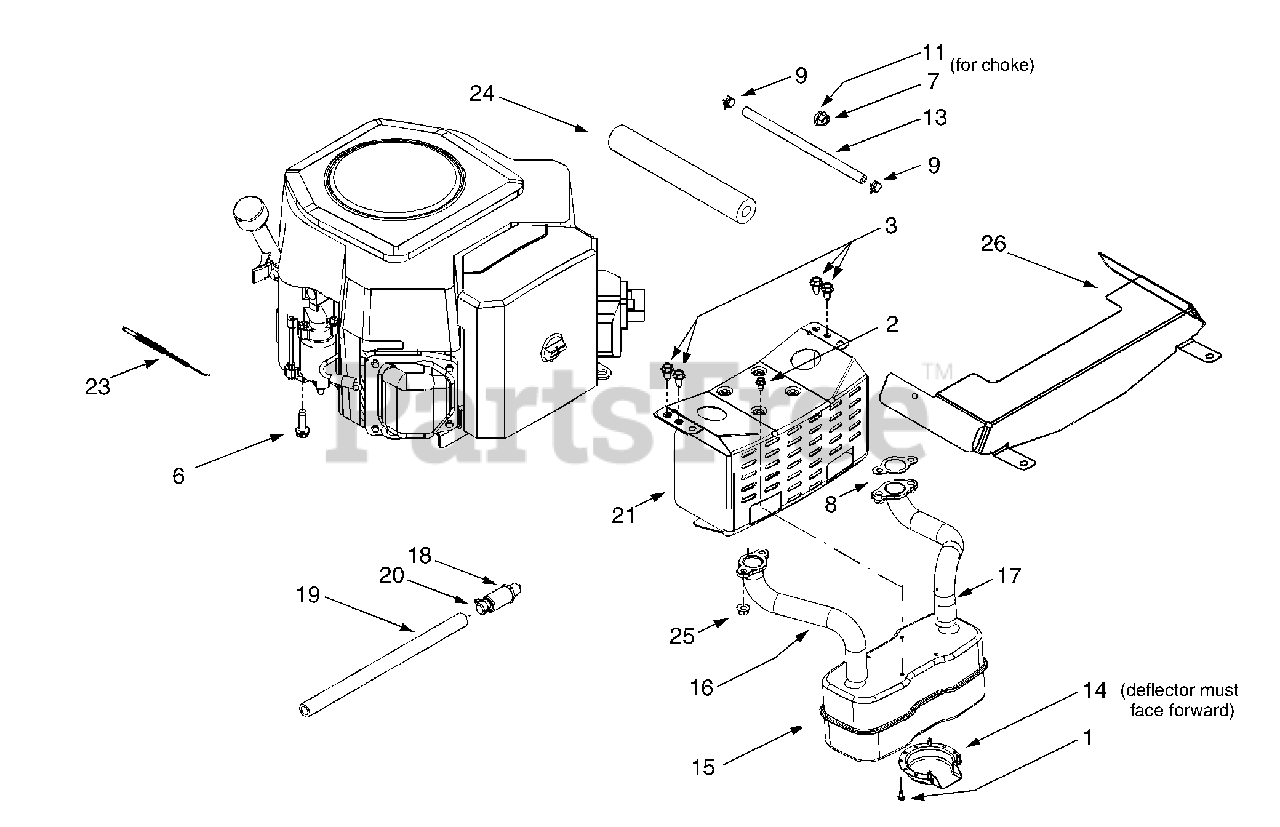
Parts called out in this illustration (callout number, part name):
1	Self Tapping Screw, #8-32 x .375
2	Self Tapping Screw, 1/4-20 x .5
3	Self Tapping Screw, 5/16-18 x .625
6	Self Tapping Screw, 3/8-16 x 1.25
7	Hex Nut, 3/8-16
8	Exhaust Gasket
9	Hose Clamp
11	Flat Washer, .406 x .875 x .059
13	Fuel Line Hose
14	Muffler Deflector
15	Muffler
16	RH Exhaust Pipe
17	LH Exhaust Pipe
18	Oil Drain Valve
19	Oil Drain Hose
20	Oil Drain Cap
23	Throttle Cable
24	Foam (fits over fuel line)
25	Flange Nut, M8 x 1.25-6
26	Heat Shield
